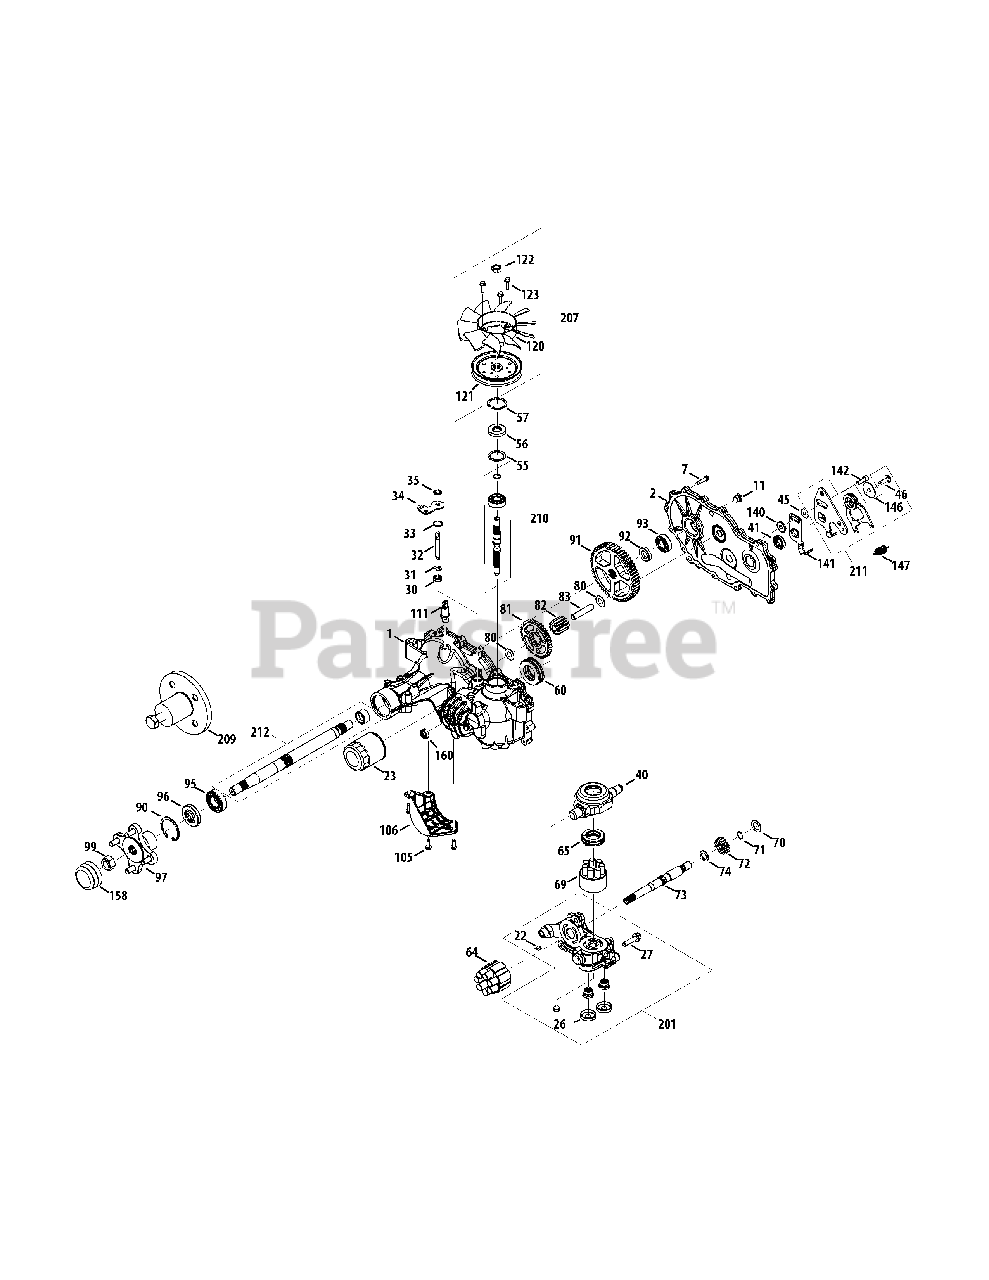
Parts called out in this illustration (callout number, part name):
1	Kit, Housing, Main, RH
2	Kit, Cover, Side, RH
7	Hex Cap Screw, 1/4-20 x 1.125
13	Sealant
22	Plate, Bypass
23	Oil Filter
26	Seal, Plug, 1.25 x .25
27	Hex Cap Screw, 3/8-16 x 1.5
30	Seal, Lip .375 x .75 x .25
31	Ring, Ret .375 External
32	Rod, Bypass
33	Ring, Ret .75 Internal
34	Arm, Bypass
35	Ring, Retaining .375 External
40	Trunnion, Swashplate
41	Seal, Lip 12 x 32 x 7
45	Washer, .34 x .88 x .06
46	Hex Cap Screw, 5/16-24 x 1.00
55	Washer, 1.23 x 1.56 x .04
56	Seal, Lip 17 x 40 x 7
57	Ring, Retaining
60	Bearing, Thrust
64	Cylinder Block Assembly
65	Thrust Ball Bearing, 30 x 52 x 13
69	Block 7 Piston Assembly
70	Washer, .63 x 1.0 x .05
71	Retaining Ring, .625
72	Gear, 16t
73	Motor Shaft
74	Washer, .72 x 1.16 x .04
80	Washer, .5 x 1.0 x .03
81	Gear, 43t
82	Gear, 11t
83	Jack Shaft
90	Retaining Ring, 2.06 Internal
91	Gear, 54t
92	Spacer, .75 x 1.32 x .257
93	Ball Bearing, .75 x 40 x 12
95	Ball Bearing, 1.0 x 52 x 15
96	Seal, Lip 25 x 52 x 10
97	Kit, Hub, 4 Bolt
99	Nut, 3/4-16, Hex Lock
105	Hex Cap Screw, 1/4-20 x .75
106	Guard, Filter, RH
111	Fitting, 9/16-18 SAE .5 Barb
120	Fan 7", 10 Blade
121	Disc, Pulley
122	Nut, 1/2-20, Hex Jam
123	Hex Cap Screw, 1/4-20 x .875
140	Spacer, .320 x 1.005 x .179
141	Neutral Left Arm
142	Hex Cap Screw, 5/16-24
146	Washer, .343 x 1.5 x .062
147	Extension Spring, .57 x 2"
160	Seal, Lip, .625 x .875 x .25
201	Kit, Center Section, RH
207	Kit, Fan & Pulley
209	Hub Puller, 4 Bolt
210	Kit, Input Shaft
211	Kit, RTN, Bidirectional
212	Kit, Shaft, Axle
